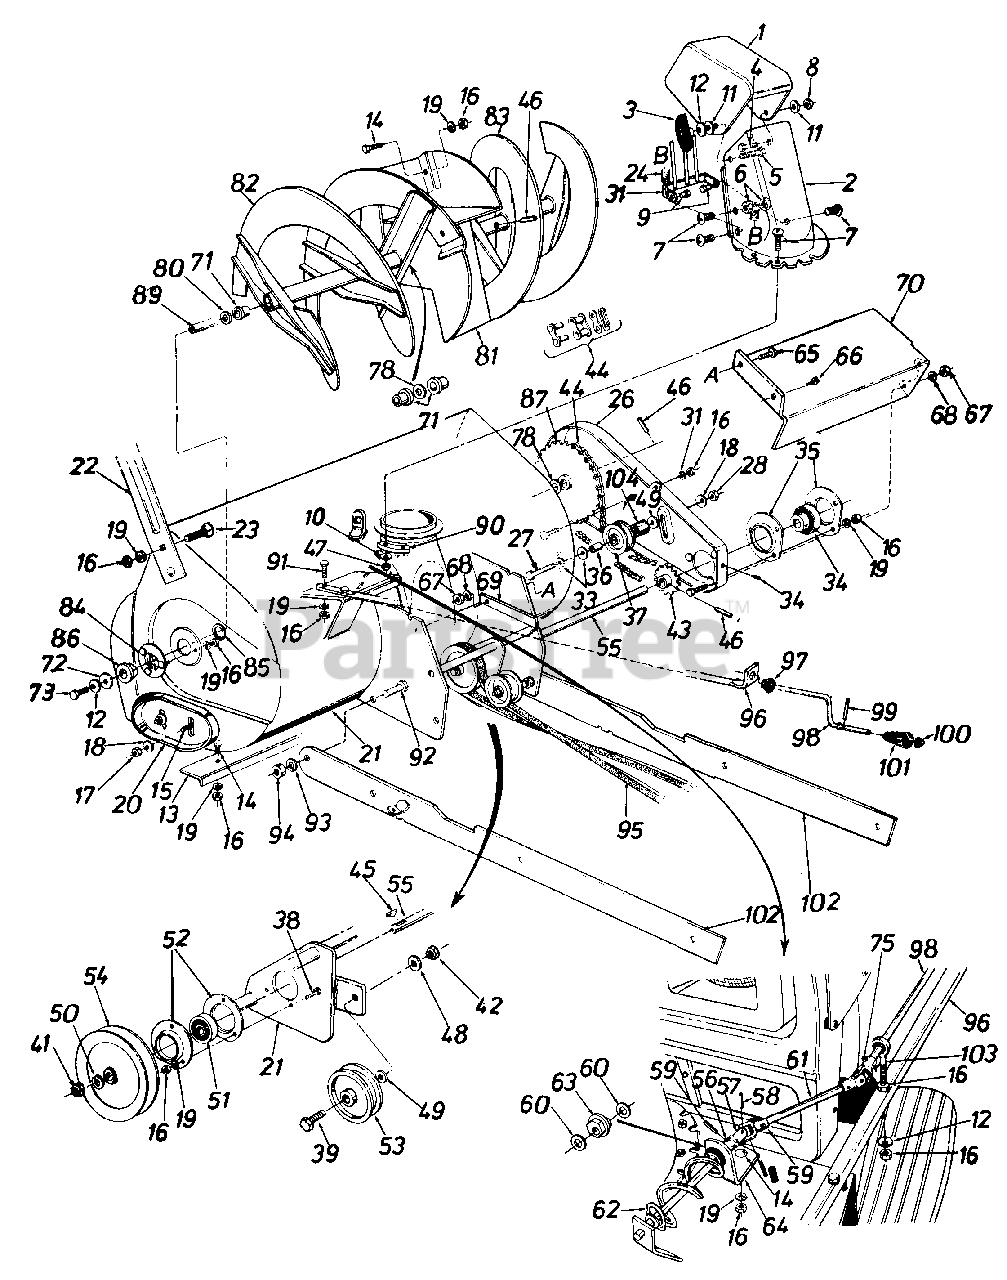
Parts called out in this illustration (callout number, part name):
1	Upper Chute
2	Lower Chute
3	Knob Handle Ass'y.
4	Truss Mach. Scr. 5/16-18 x .75" Lg.
5	Carriage Bolt 5/16-18 x 1.0"
6	Hex Cent. L-Nut 5/16-18 Thd.
7	Truss Mach. Scr. 1/4-20 x .75" Lg.
8	Hex Cent. L-Nut 5/16-18 Thd.
9	Shld. Nut 1/4-20 Thd.
10	Fl. Wash. 1/4" I.D.
11	Fl.-Wash. .344" I.D. x 1.125"
12	Bell. Wash. .345" I.D. x .88"
14	Carriage Bolt 5/16-18 x .62"
15	Carriage Bolt 3/8-16 x .62"
16	Hex Nut 5/16-18 Thd.
17	Hex Jam Nut 3/8-16 Thd.
18	Bell. Wash. .40 I.D. x .88"
19	L.-Wash. 5/16" I.D.
20	Slide Shoe
21	Spiral Hsg. Ass'y.-36"
22	Guide Blade
23	Carriage Bolt 5/16-18 x .62" Lg.
24	Extension Spring
26	Chain Guard Ass'y.
27	Hex Bolt 3/8-16 x 2.00 Lg.
28	Hex Inst.-Nut 3/8-16 Thd.
33	Fl.-Wash. .385" I.D. x .87" O.D.
34	Ball Brg. .75" I.D.
35	Flangette
36	Spacer.375" I.D. x .60" O.D.
37	Fl.-Idler w/Flanges 1.875
38	Hex Sems Bolt 5/18x.75" Lg.
39	Hex Bolt 3/8-16 x 1.75" Lg.
41	Hex Jam Nut 3/4-10 Thd.
42	Hex Jam Nut 3/8-16 Thd.
43	Sprocket Ass'y. 14 Teeth
44	#420 Chain x 1/2" Pitch 77 Links
45	#61 Hi-Pro-Key 3/16 x 5/8"
46	Spring Pin Spir. 5/16" Dia. x 1.75" Lg.
47	Hex L-Nut 1/4-20 Thd.
48	L.-Wash. 3/8" I.D.
49	Fl.-Wash. .406" I.D. x 1.25"
50	Spring L.-Wash. 3/4" I.D.
51	Self-Aligning Brg.
52	Flangette
53	Idler Pulley
54	5/8 V Pulley .75" I.D. x 6"
55	Drive Shaft Ass'y
56	Joint Brkt. Ass'y.
57	Joint Block
58	Oval Head Rivet
59	Spiral Pin 1/8" Dia.
60	Fl.-Wash. .385" I.D. x .62"
61	Chute Crank Ext. Rod
62	Chute Crank Ass'y. R.H.
63	Plastic Bushing .380" I.D.
64	Chute Crank Brkt.
65	Hex Boit 1/4-20 x .62" 4.
66	Hex Wash. S-Tap Scr. 1/4-20 x .50" Lg.
67	Hex Nut 1/4-20 Thd.
68	L.-Wash. 1/4" I.D.
69	Belt Cover
70	Drive Shaft Cover
71	Plastic Bushing
72	Washer .39" I.D. x 1.75" O.D
73	Hex Bolt 5/16-18 x .88" Spec
75	Cotter Pin 3/32" Dia.
78	Fl.-Wash. 1.03" I.D. x 1.62"
80	Fl.-Wash. 1.0" x 1.75"
85	Snap Ring for 1.50" Shaft
86	Flange Brg. w/flats 1.00" I.D.
87	Sprocket Hub Ass.y. 40 Teet
89	Spiral Axle
90	Chute Flange Keeper
91	Hex Bolt 5/16-18 x 1.5" 4.
92	Hex Bolt 1/2-13 x 1.25" 4.
93	L.-Wash. 1/2" I.D.
94	Hex Nut 1/2" 13 Thd.
95	"V"Belt
98	Chute Crank 34.5" L.g
99	Roll Pin .12 Dia. x .63
100	Push Nut 3/8" Rod
101	Knob Black
102	Linkage Arm
103	Eye Bolt 5/16-18 x 3.0" Lg.
104	Idler Spacer
